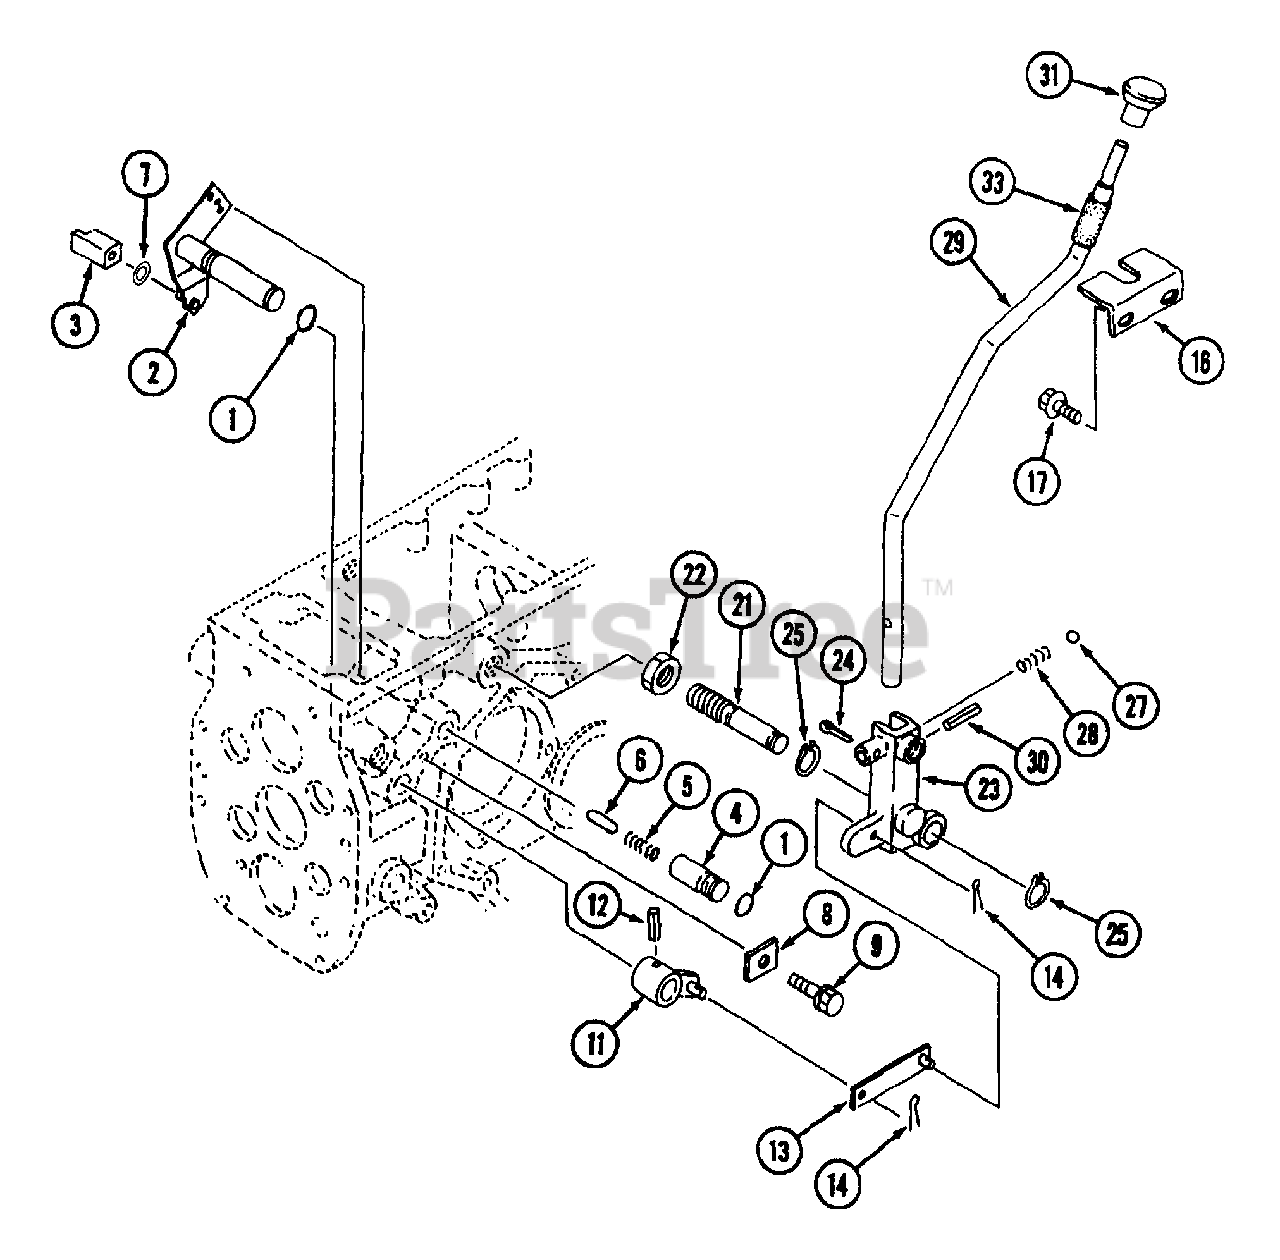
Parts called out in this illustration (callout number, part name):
2	Shifter, Range
14	Pin, Split
23	Bracket, Range
